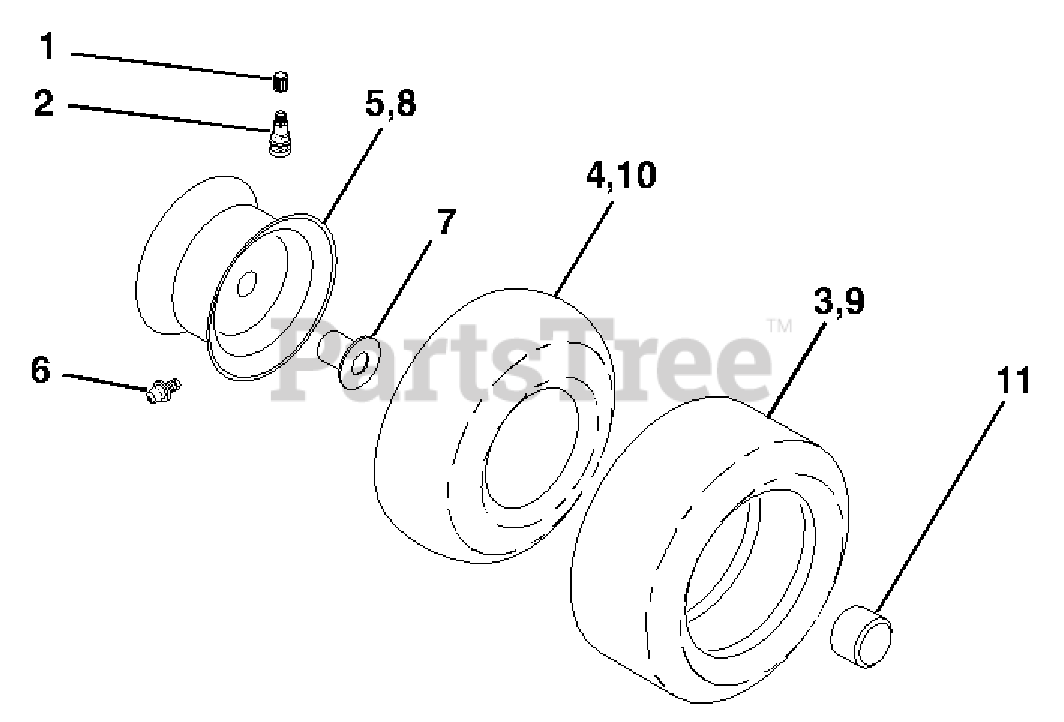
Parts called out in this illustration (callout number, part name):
1	Cap Valve Tire
2	Stem Valve
3	Tire F T 15 x 6 0- 6 Service
4	Tube Front
5	Rim Asm 6" front Service
6	Fitting Grease
7	Bearing Flange
8	Rim Asm 8" rear Service
9	Tire R T 20 x 10-8 Service
10	Tube Rear
11	Cap Axle Blk 1 50 x 1 00
